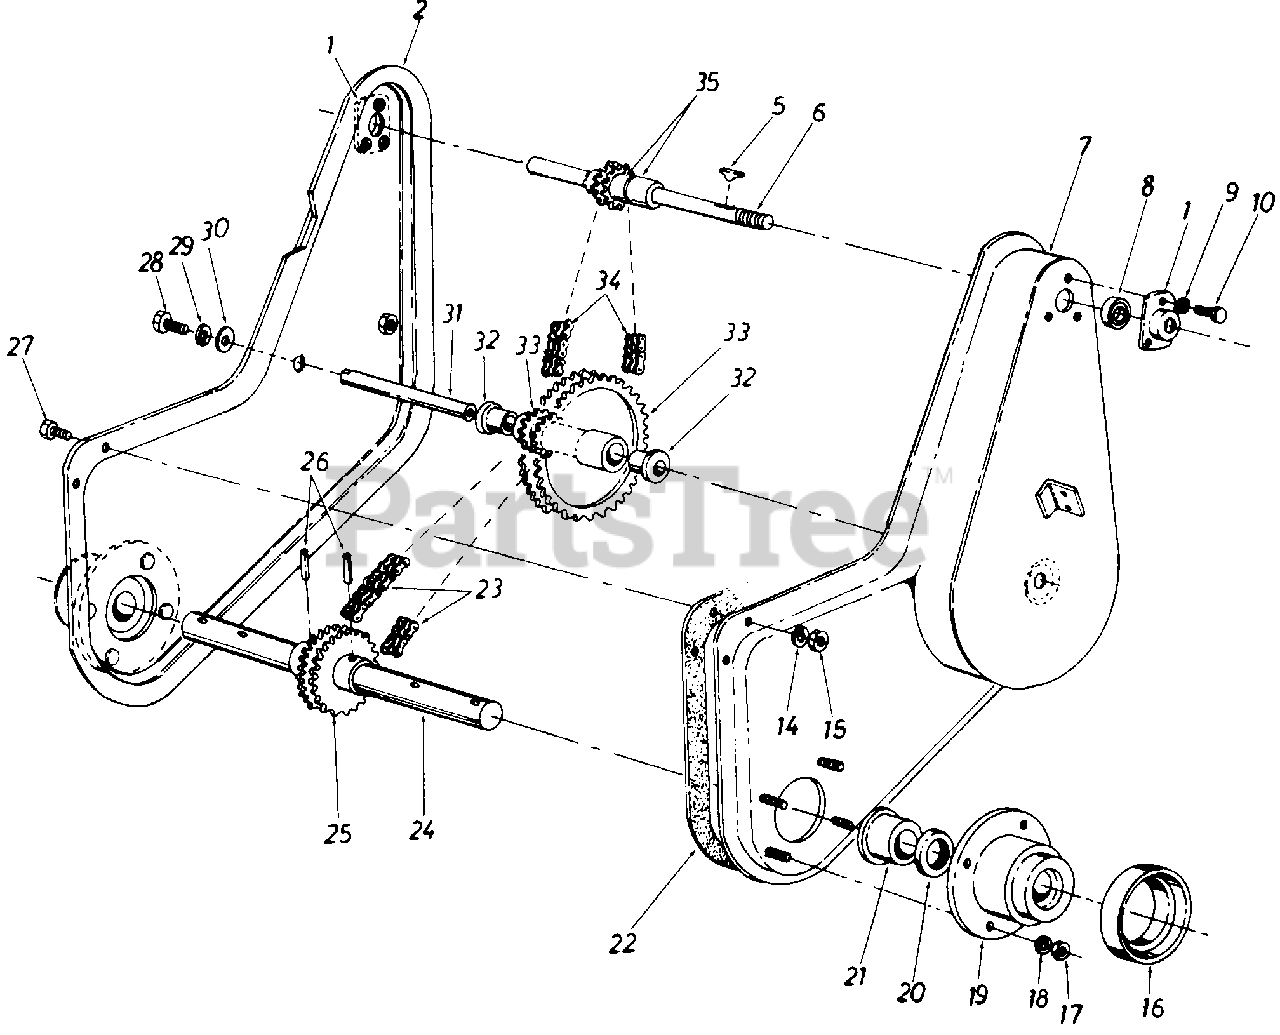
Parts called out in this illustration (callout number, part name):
1	Bearing Housing 1.375" Dia.
6	Input Shaft Assembly
9	L-Wash. 1/4" I.D.
10	Hex Bolt 1/4-20 x .62" Lg.
14	L-Wash. 1/4" I.D.*
15	Hex Cent. L-Nut 1/4-20 Thd.
16	Dust Cap Cover
17	Hex Cent. L-Nut 5/16-18 Thd.
18	L-Wash. 5/16" I.D.*
19	Cast Bearing Housing
20	Oil Seal
21	Flange Bearing 1.25" I.D. x 1 .75" O.D.
23	Roller Chain #40-2 x 34.0"-Lg.
25	Double Sprocket T24-2 Teeth 1/2" Pitch
26	Spiral Pin 3/8" Dia. x 2.00"-Lg.
27	Hex Bolt 1/4-20 x .62" Lg.
28	Hex Bolt 5/16-18 x .75" Lg.
29	L-Wash. 5/16" I.D.
30	Fl-Wash. 5/16" I.D.
31	Sprocket Shaft
32	Flange Bearing .62" I.D. x .75" O.D.
33	Double Sprocket Assembly
34	Roller Chain #35-2 x 36.75" Lg.
35	Spacer 5/8" I.D. x 7/8" O.D.
14895-0637	HOUSING-RH - POWDER BLACK (0637)
